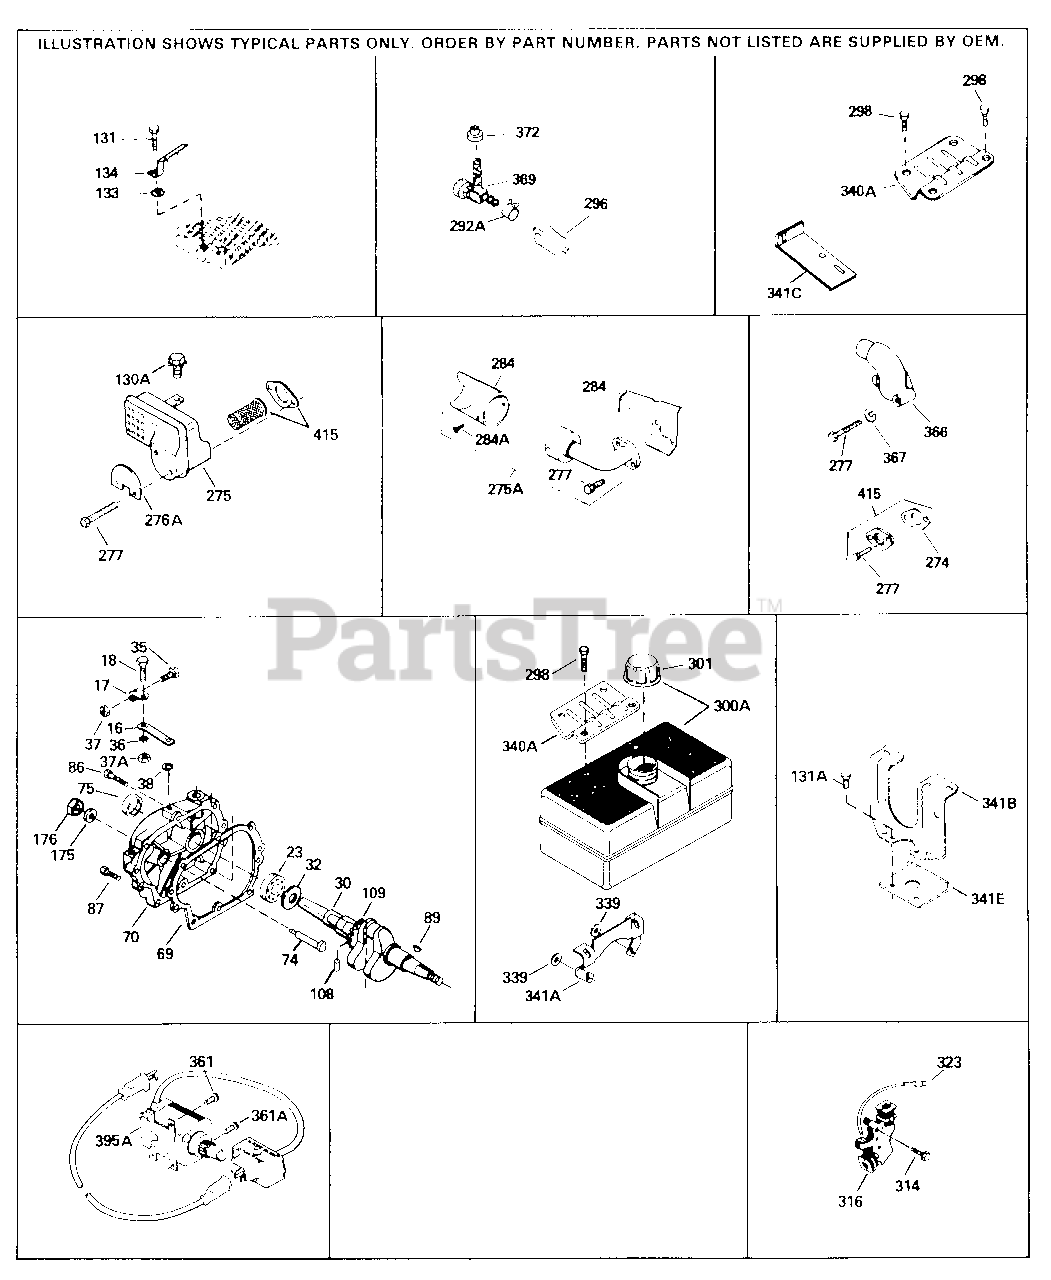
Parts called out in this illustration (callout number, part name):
16	Governor Lever Assy.
17	Governor Lever Clamp
18	Screw, 8-32 x 5/16"
23	Bearing, Ball
30	Crankshaft (Incl. 108 & 109)
32	Washer, Thrust
35	Screw, 10-32 x 3/4"
36	Lock Washer #8
37	Lock Nut, 10-32
37A	Lock Nut, 8-32
69	* Gasket, Cylinder cover
70	Cyl.Cover Incl. 71,74,75,80,175,176,3 1 1,312
74	Retainer, Bearing
75	Seal, Oil
86	Screw, 1/4-20 x 1-1/4"
87	Screw, 1/4-20 x 1-3/4"
89	Key, Flywheel
108	Pin, Crankshaft gear
109	Gear, Crankshaft
130A	Screw, 5/16-18 x 1-1/2" Use as req.,b ut not w/650691 washer
131	Screw, 1/4-20 x 5/8 (Use as required)
131	Screw, 1/4-20 x 5/8" Use as required
131A	Screw, 5/16-18 x 5/8" Use as require d
133	Washer, Lock, 5/16"
134	Clip, Spark plug shorting
175	Lockwasher
176	Nut, Lock, 10-24
274	Gasket, Exhaust (Use as required)
275	Muffler
277	Screw, 5/16-18 x 3-3/16"
298	Screw, 1/4-15 x 7/8"
301	Fuel Cap (Red)
341C	Bracket, Fuel tank mounting
370J	Decal, Instruction Can be used on HM8 0 with diecast starter.
415	Exh.Adaptor Kit (Incl. 274,277) As re quired
